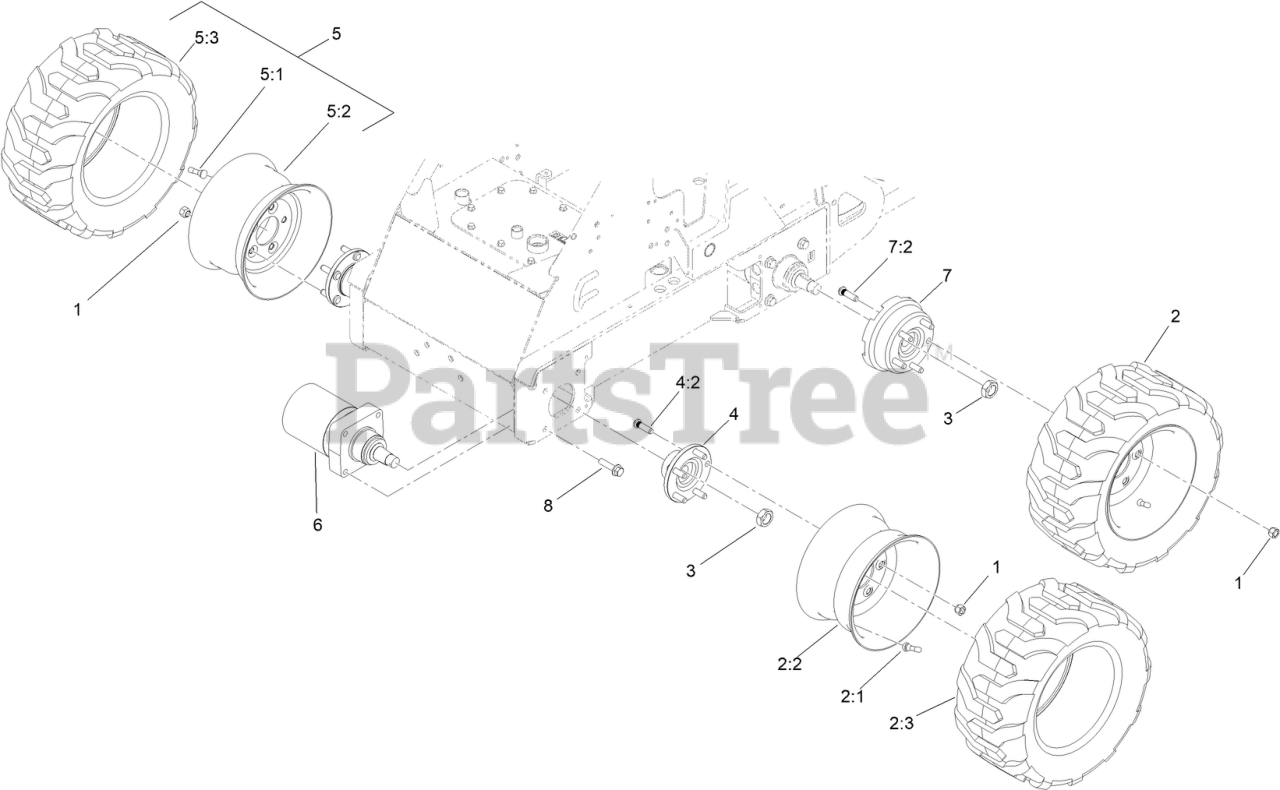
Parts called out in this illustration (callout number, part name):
1	NUT-LUG
2	TIRE AND WHEEL ASM, LH
2:2	WHEEL-10X6.00, 5 BOLT
2:3	TIRE-18X8.50-10
3	NUT-LOCK
4	HUB ASM
4:2	STUD-TYPE, DRIVE
5	TIRE AND WHEEL ASM, RH
5:2	WHEEL-10X6.00, 5 BOLT
5:3	TIRE-18X8.50-10
6	HYD MOTOR ASM
7	WHEEL HUB ASM
7:2	STUD-TYPE, DRIVE
8	SCREW-HHF
